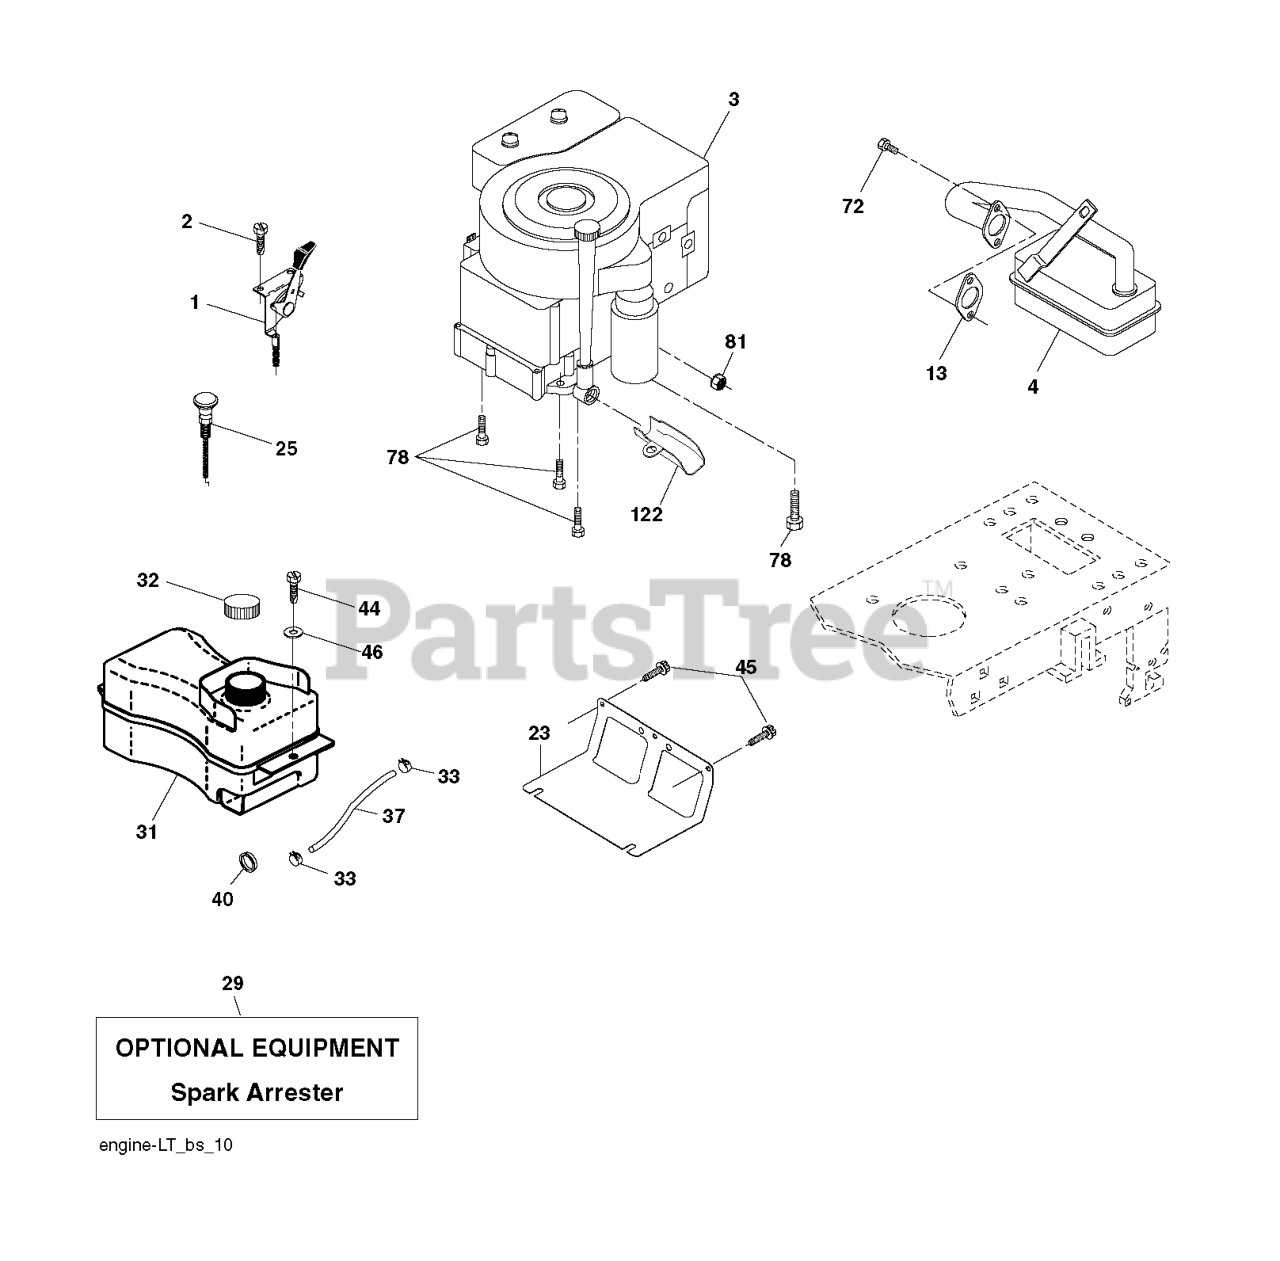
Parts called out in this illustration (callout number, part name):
1	CONTROL.THROTTLE/CHOKE.BLACK
2	SCREW
4	MUFFLER.B&S.MODEL.21.11HP.OHV
13	REPL BY 532 27 22-93
23	SHIELD.BROWNING.DBR.GUARD
25	KNOB.ERGO.EXTENDED.RED (1 2)
29	KIT.SPARK ARRESTOR 794945 B&S
32	CAP ASM.FUEL.2.25"FR.
33	HOSE CLAMP
37	LINE.FUEL.20
40	BUSHING.SNAP.NYL.BLK.
44	SCREW HEXWSHR 1/4-20X3/4
45	SCREW, 3/8-16X3/4
46	WASHER
72	SCREW.SOCKET HD.5/16-1
78	SCREW.3/8-16
81	NUT
122	EXTENSION DRAIN OIL
